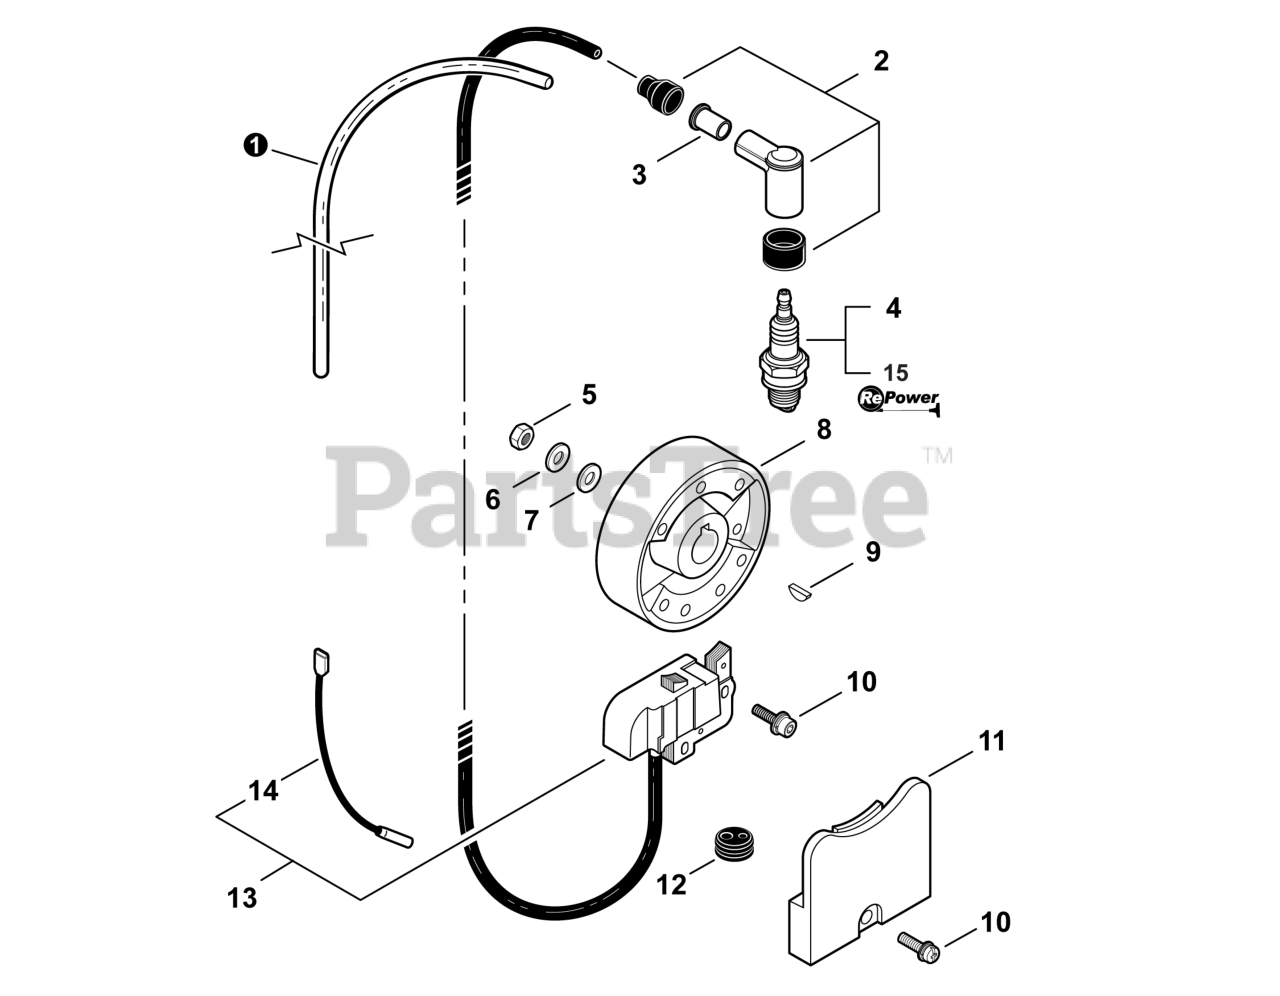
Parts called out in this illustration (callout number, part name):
1	TUBE, VINYL 6.3×8×380
2	CAP, SPARK PLUG
3	ADAPTOR, SPARK PLUG - CAP
4	SPARK PLUG - BPMR8Y
6	WASHER, SPRING 10
7	WASHER, SPRING 10
8	FLYWHEEL
9	KEY, WOODRUFF 3×14
10	BOLT 5×22
11	COVER, DUST
13	COIL ASSY, IGNITION
14	LEAD - IGNITION
15	TUNE-UP KIT - REPOWER
